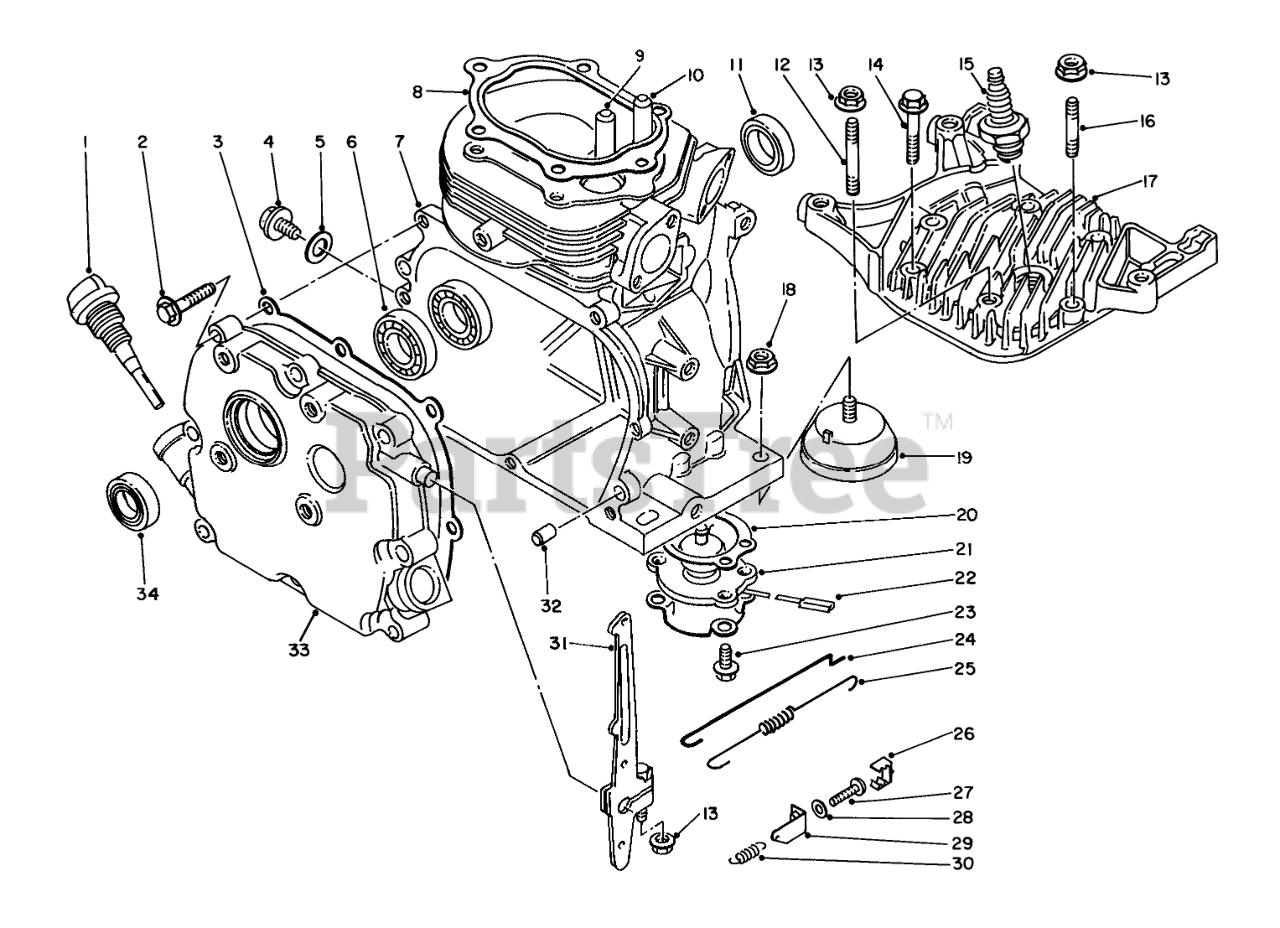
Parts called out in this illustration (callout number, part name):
1	Gauge-Oil Level
3	CRANKCASE GASKET
4	Bolt
5	Gasket
6	Bearing
7	Cylinder Assembly
8	CYL. GASKET
9	Guide-Exhaust Valve
10	Guide-Intake Valve
11	OIL SEAL
12	Bolt-Stud
15	SPARK PLUG
16	Bolt-Stud
17	Cylinder Head
19	MOUNTING
20	GASKET
21	SENSOR
22	Plate
24	Rod-Carburetor
25	SPRING
27	Screw
28	Washer
29	Hook-Governor
30	SPRING
31	Lever-Throttle Conlrol
33	Cover-Crankcase Side
34	OIL SEAL
